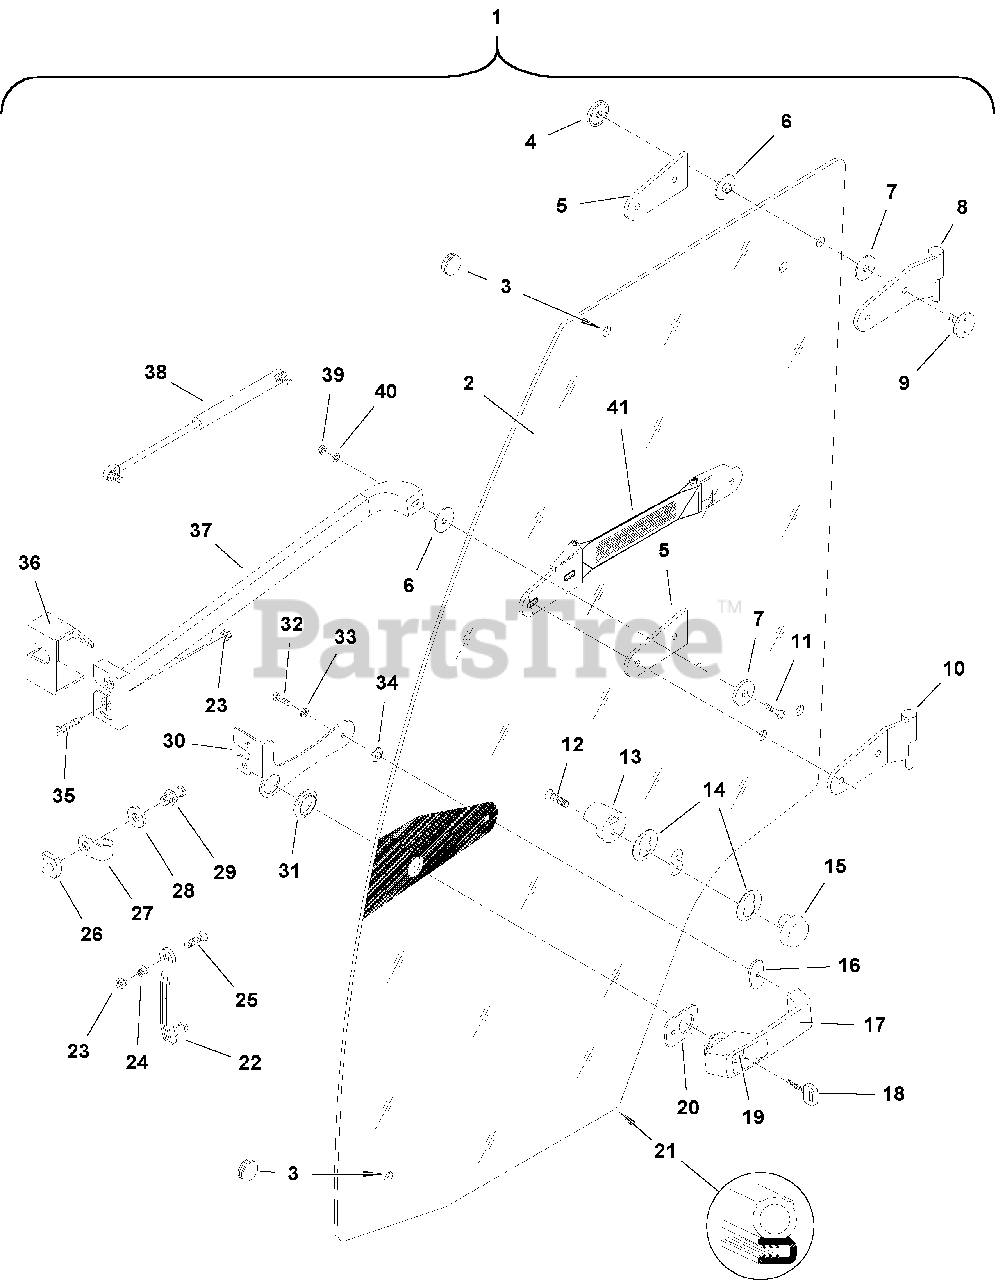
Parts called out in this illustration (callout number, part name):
1	LEFT DOOR, Complete, (Includes Ref. 2 - 41)
1	RIGHT DOOR, Complete, (Includes Ref 2 - 41)
2	LEFT DOOR, Glass
2	RIGHT DOOR, Glass
3	RUBBER STUBBLE, DM 16
4	WASHER, with Bushing, M8
5	INNER BRACKET, Hinge
6	WASHER, Rubber with Socket
7	WASHER, Rubber
8	DOOR HINGE, Upper Right
8	DOOR HINGE, Upper Left
9	PVC-WASHER, with Screw, M8 x 30
10	DOOR HINGE, Lower Right
10	DOOR HINGE, Lower Left
13	BEARING, Inner Gas Spring
14	WASHER, Rubber
15	BEARING, Outer Gas Spring
16	RUBBER PAD, Small
17	DOOR HANDLE, with Door Lock
18	KEY, (NR. 14603)
20	RUBBER PAD, Large
21	PROFILE SEALING, 23 ft. 3 in.
22	BAR, Door Holding
26	BRACKET, Threaded
27	GLIDE, Metal
29	LOCKING BOLT, 13mm
30	LOCKER BRACKET, Left Door
30	LOCKER BRACKET, Right Door
31	RUBBER PAD, with Socket, Large
34	RUBBER PAD, with Socket, Small
36	DOOR LOCK COVER, Left
36	DOOR LOCK COVER, Right
37	INNER DOORLOCK, Left w/ Handle
37	INNER DOORLOCK, Right w/ Handle
38	GASLIFT, 320MM 300N
41	STRAP, Door Stop
